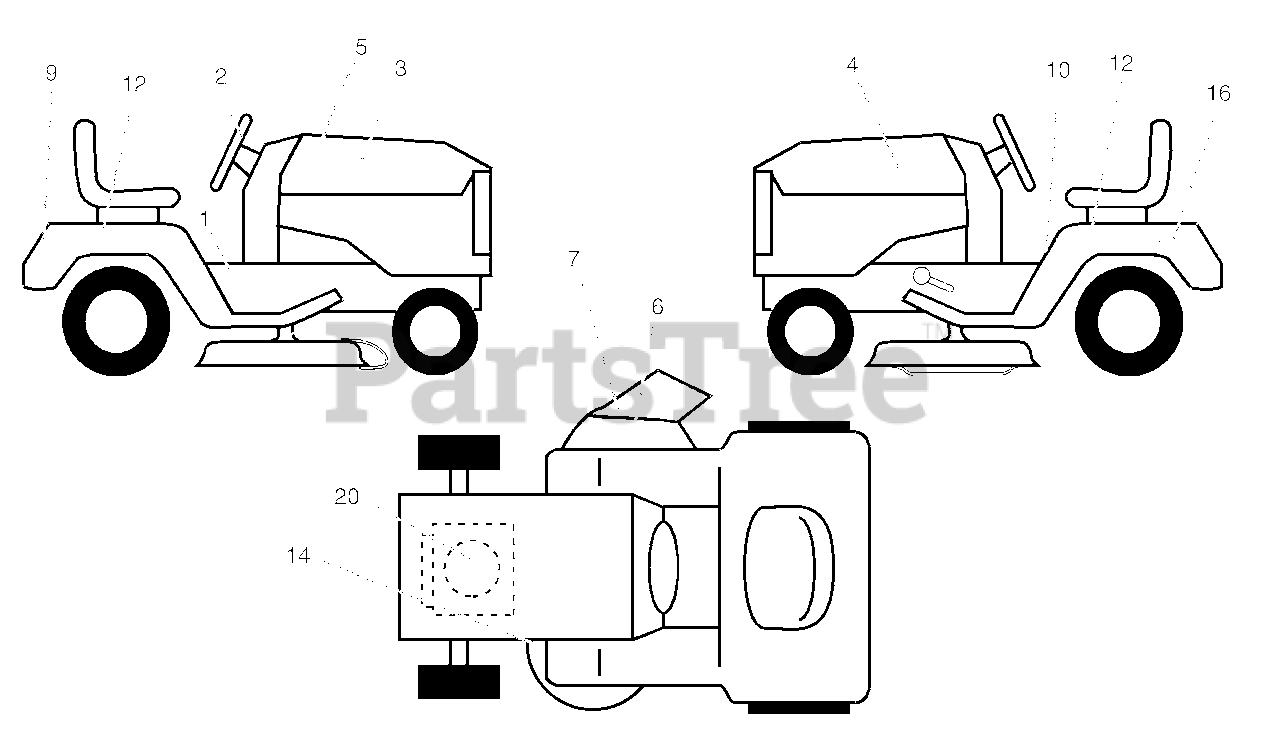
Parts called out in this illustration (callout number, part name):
1	Decal Instruction
2	Decal Ins Strg Wh
3	Decal Hood Rh
4	Decal Hood Lh
5	Decal Replacement
6	Decal, Warning
7	Decal Deck "B" 42"
9	Decal Fender Logo
10	Decal Danger English
12	Decal Fender
14	Decal V-belt Schematic 42"
16	Decal Battery Danger/Poison
20	Decal HP Engine
